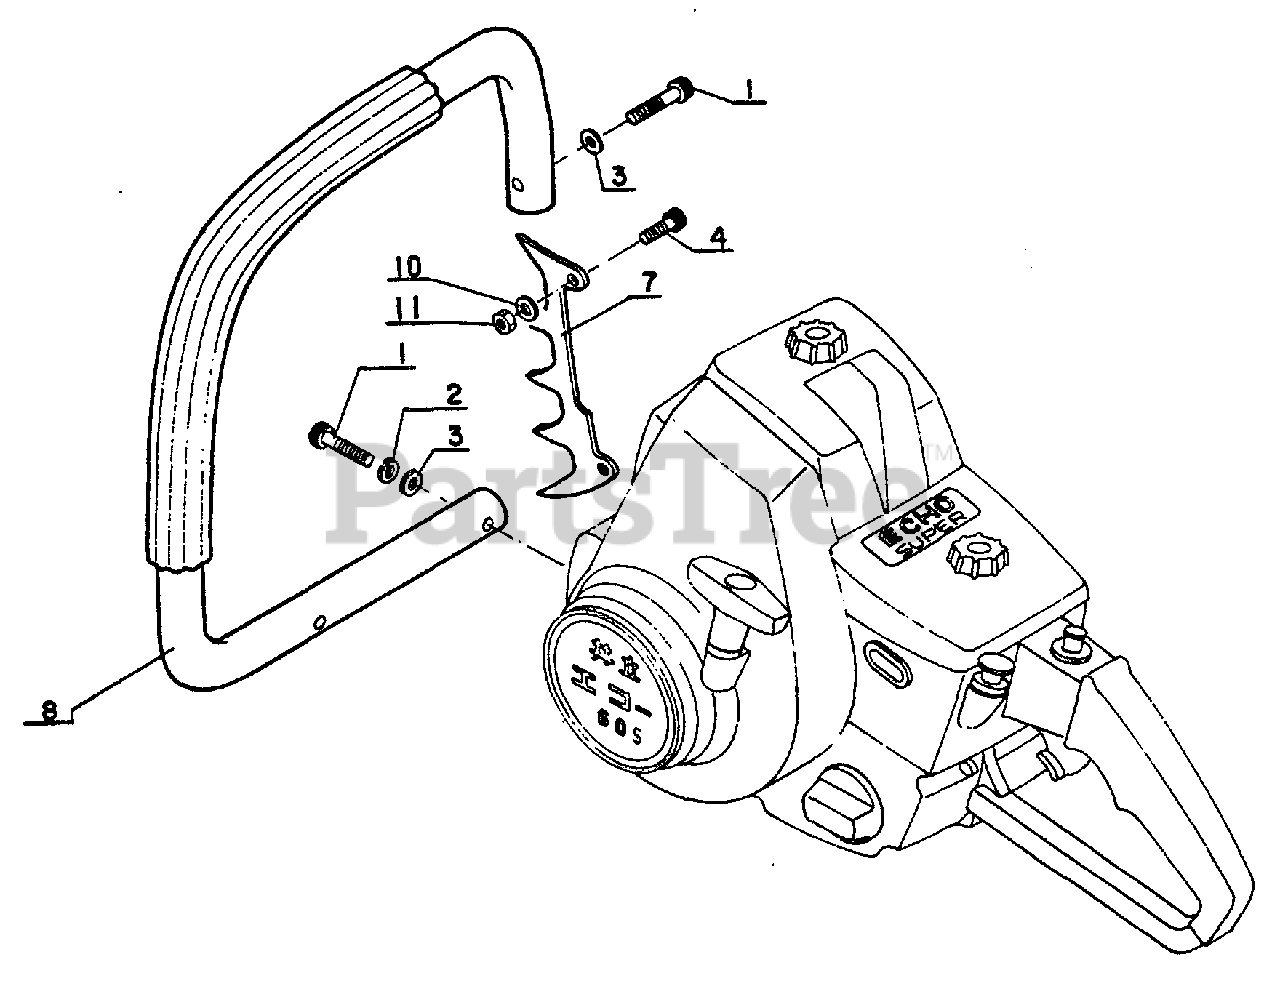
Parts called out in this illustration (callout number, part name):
1	SCREW - 6×32
2	WASHER, SPRING 6
3	WASHER 6.5×11.5×0.8
4	BOLT M5×18
7	BUMPER, SPIKED
8	LEFT HANDLE
10	WASHER, FLAT 5.5×10×0.8
11	LOCKNUT - 5
